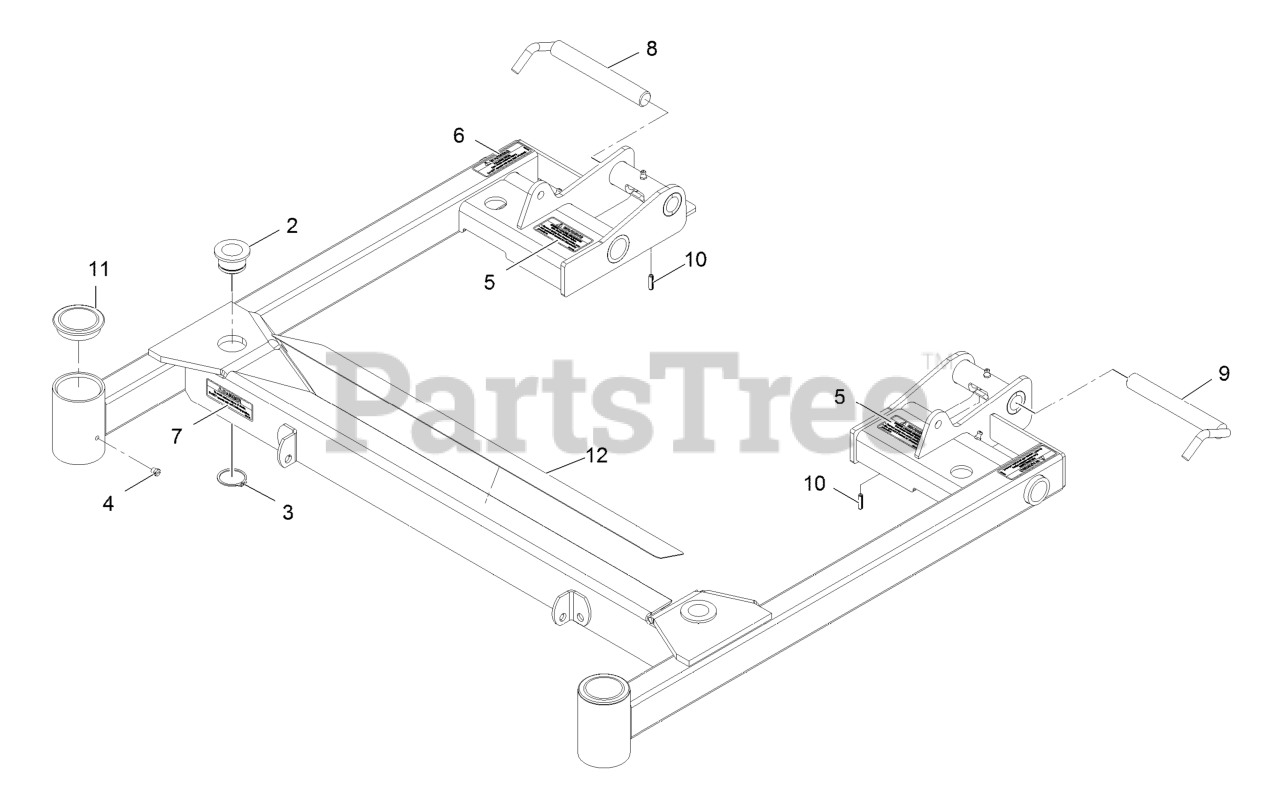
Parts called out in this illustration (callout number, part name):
2	BUSHING-SUPPORT, DECK
3	RING-RETAINING
5	DECAL-SPRING
6	DECAL-FOLDING DECK
7	DECAL-DANGER
8	LOCK-DECK, RH
9	LOCK-DECK, LH
10	PIN-SPRING
11	CAP-GREASE
12	PAD-ANTI SKID
